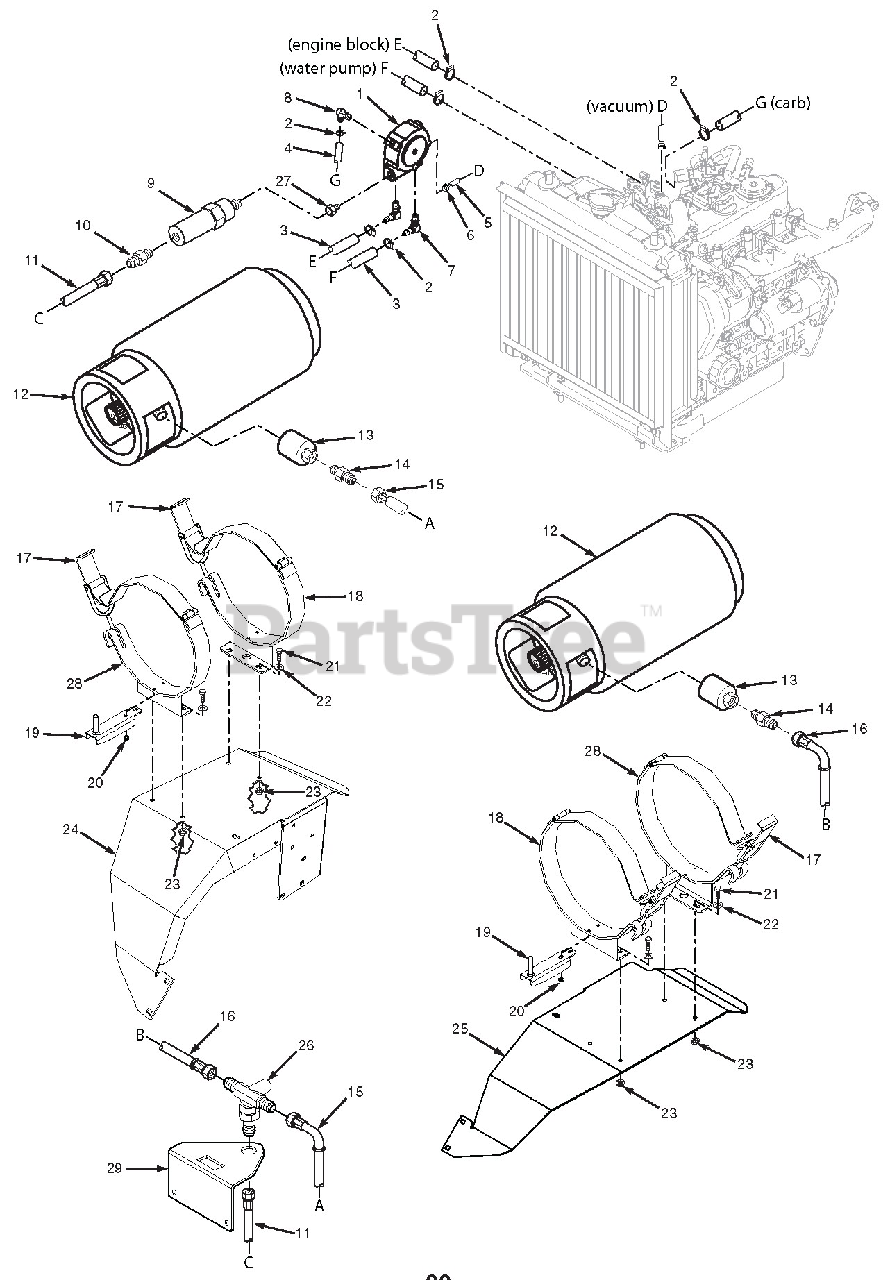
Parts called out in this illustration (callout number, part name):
1	Regulator, Kubota
2	Clamp, 0.87 Max. Dia.
3	Hose, 3/8" ID 300 PSI
4	Hose, LP
5	Hose, Vacuum Line
6	Clamp, 3/16" Hose ID
7	Fitting, 90 Degree - Kubota
8	Fitting, 90 Degree - Kubota
9	Lockoff Valve LP, Electric
10	Fitting, Union 3/8" Flare x 1/4" Pipe
11	LP Fuel Line, 45-1/2" (to Regulator)
12	LP Fuel Tank
13	LP Quick Coupler
14	Fitting, Union 3/8" Flare x 1/4" Pipe
15	LP Fuel Line, 26-1/2" (RH Tank)
16	LP Fuel Line, 52" (LH Tank)
17	LP Tank Lock Bracket
18	Front LP Tank Mounting Bracket
19	LP Tank Locating Bracket
20	Bolt, 1/4-20 x .375"
21	Bolt, Hex Head 3/8-16 x 1"
22	Flatwasher, 3/8-.391 x .938 x .105
23	Nut, Serrated Flange 3/8-16
24	Fender Weldment, RH
25	Fender Weldment, LH
26	T-Connector, w/check valves
27	Fitting, Kubota
28	Rear LP Tank Mounting Bracket
29	Mounting Bracket, Tee Fitting and Selector Switch
